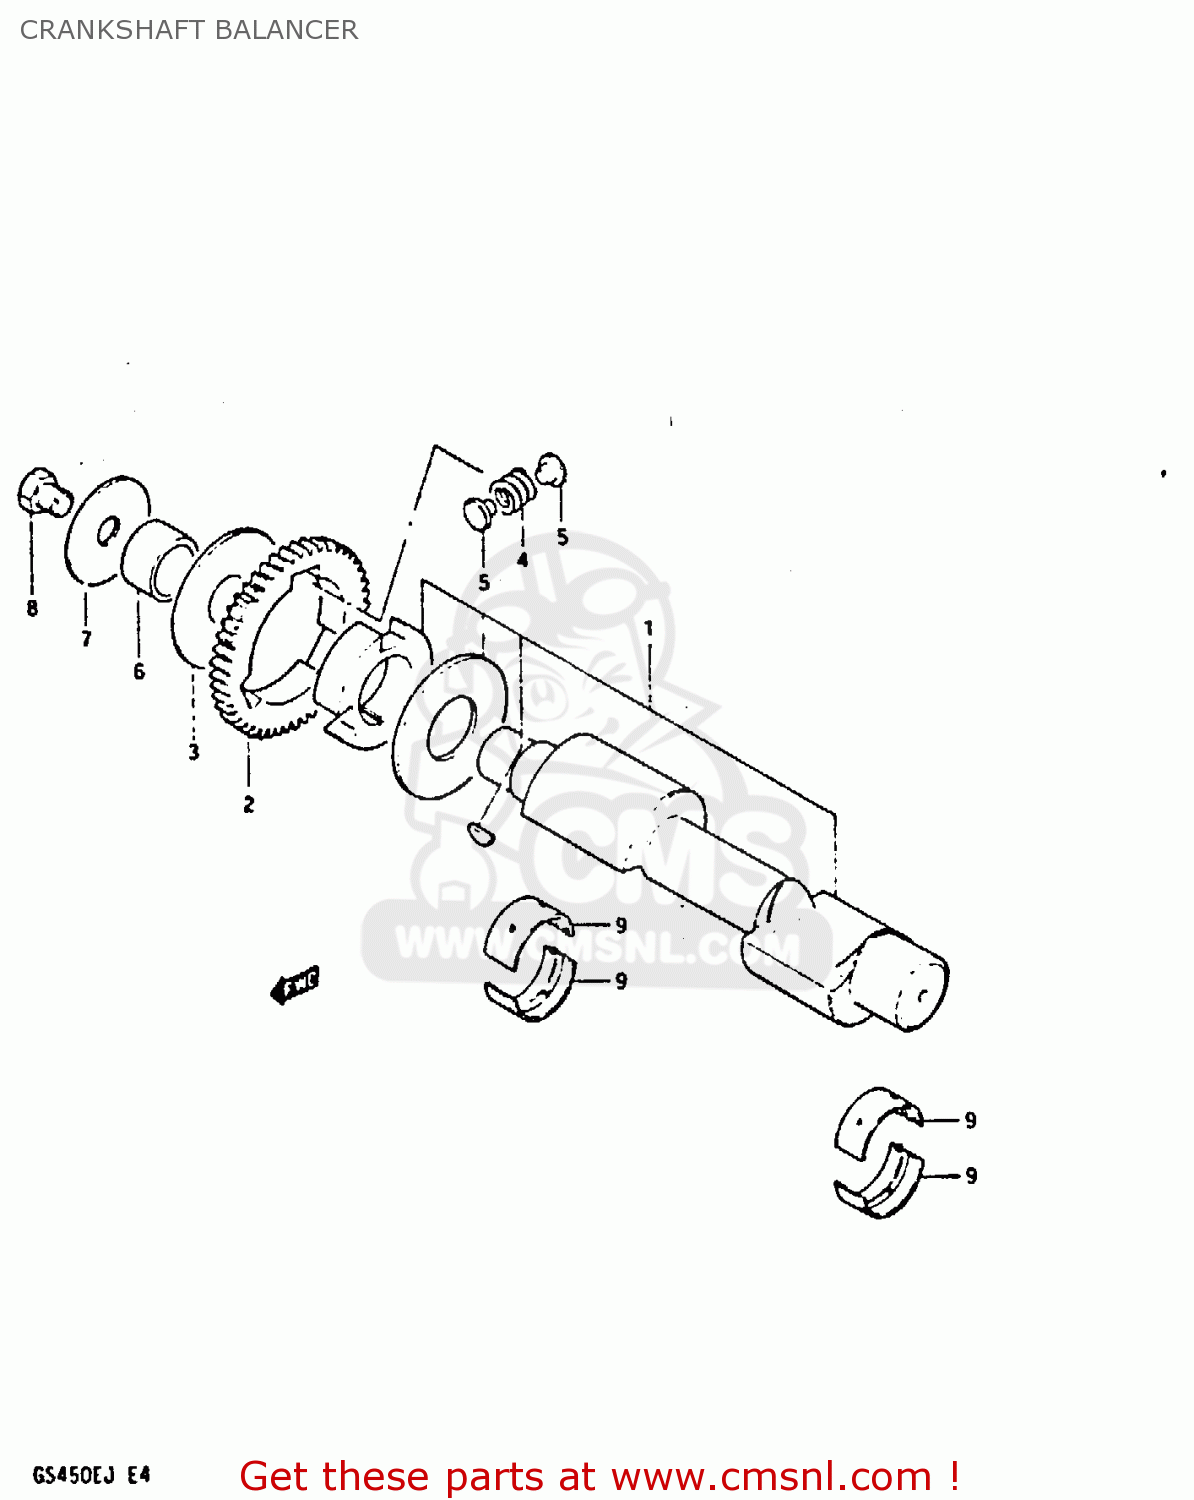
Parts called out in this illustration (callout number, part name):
1	BALANCER,CRANKSHAFT
2	GEAR,CRANK BALANCER DRIVE
3	WASHER
4	SPRING
5	PIN
6	SPACER
7	WASHER(12X50X3)
8	BOLT
9	METAL CRANKSHAFT
